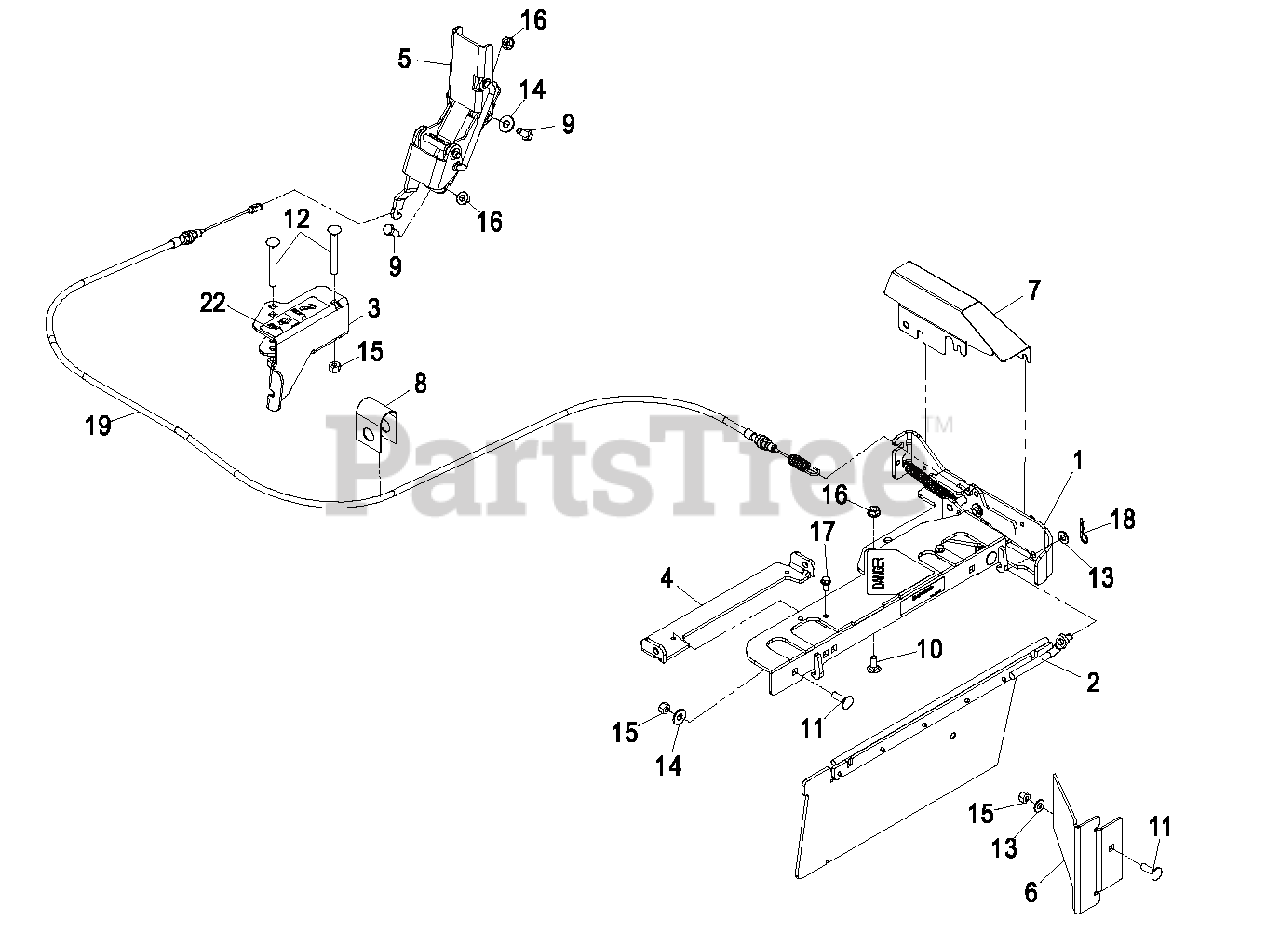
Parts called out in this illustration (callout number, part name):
1	ASM,GATE LINKAGE
2	ASM,GATE OCDC
3	ASM,CABLE BRACKET W/DECAL
4	BRACKET,CHUTE PIVOT
5	ASM,PEDAL - OCDC GATE
6	PLATE,FILLER
7	COVER,GATE LINKAGE
8	STRAP,CABLE HANGER
9	SCREW-HH
10	BOLT-CARR
11	BOLT-CARR
12	SCREW-CARR
13	WASHER-PLAIN
14	WASHER-FLAT
15	NUT-LOCK, NI
17	SCREW-HWH
18	PIN-COTTER
19	CONTROL,DISCHARGE GATE
22	DECAL,OCD5 OPERATION
